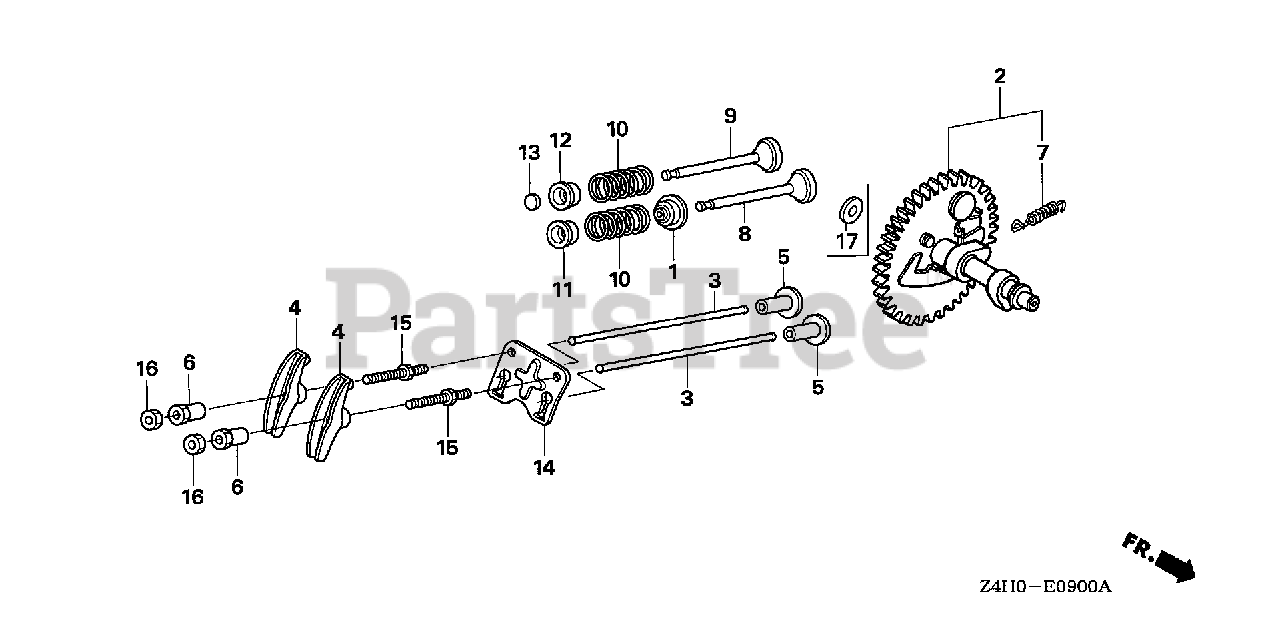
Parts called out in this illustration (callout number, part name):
1	SEAL, VALVE STEM
2	CAMSHAFT ASSY.
3	ROD, PUSH
4	ARM, VALVE ROCKER
5	LIFTER, VALVE
6	PIVOT, ROCKER ARM
7	SPRING, WEIGHT RETURN
8	VALVE, IN.
9	VALVE, EX.
10	SPRING, VALVE
11	RETAINER, IN. VALVE SPRING
11	RETAINER, VALVE SPRING (EXHAUST SIDE)
12	RETAINER, EX. VALVE SPRING
12	RETAINER
13	ROTATOR, VALVE
14	PLATE, PUSH ROD GUIDE
15	BOLT, PIVOT (8MM)
16	NUT, PIVOT ADJ.
